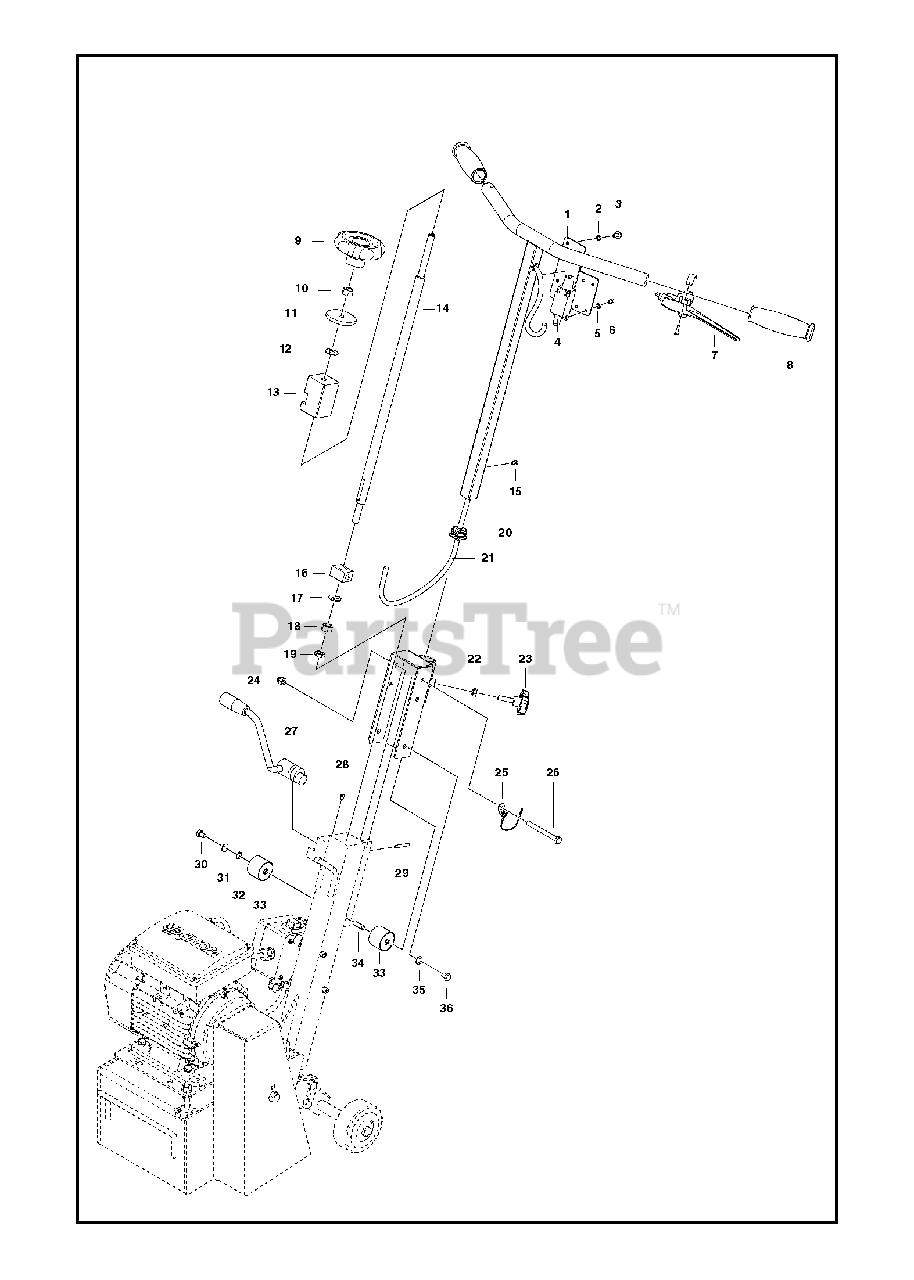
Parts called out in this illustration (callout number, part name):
1	SUPPORT SHEETOnly electric verison
2	LOCKWASHEROnly electric verison
3	SCREWOnly electric verison
4	MICRO SWITCHOnly electric verison
5	LOCKWASHEROnly electric verison
6	SCREW IHSCMOnly electric verison
22	HEXAGON LOCKING NUT
